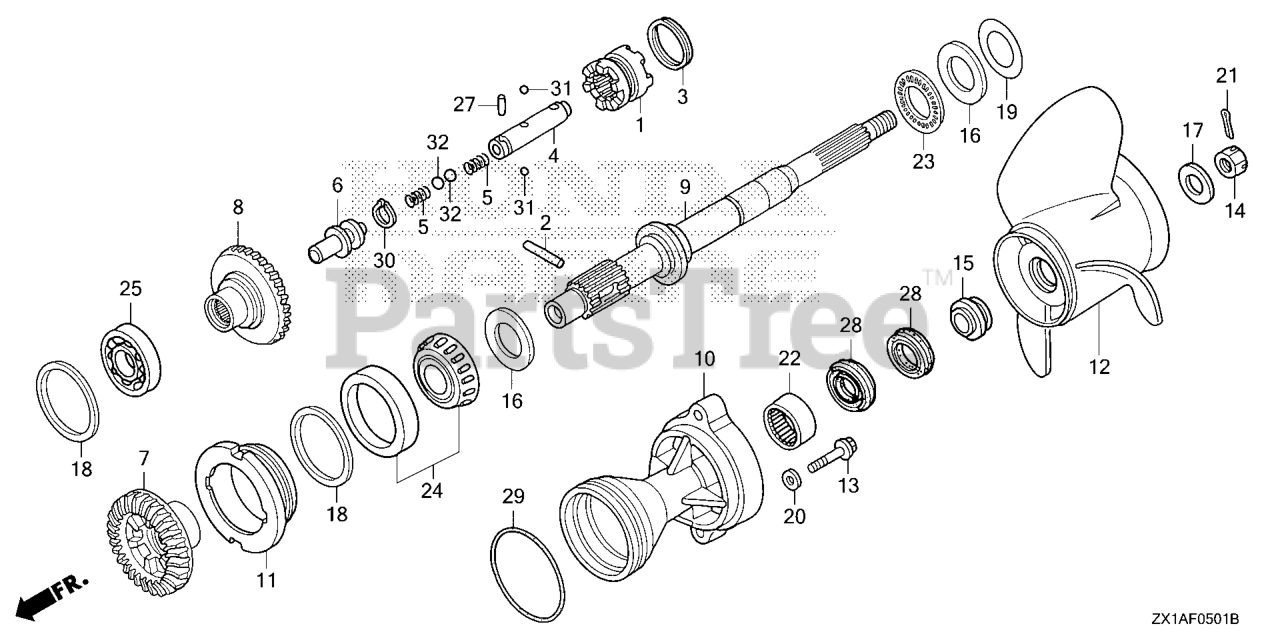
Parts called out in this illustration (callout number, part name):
1	SHIFTER, CLUTCH
2	PIN, SHIFTER (8X47)
3	RING, CROSS PIN
4	SLIDER, SHIFT
5	SPRING, SHIFT
6	PLATE, SHIFT
7	GEAR, BEVEL (FORWARD 30T) (COUNTER ROTATION)
8	GEAR, BEVEL (RVS. 30T) (COUNTER ROTATION)
9	SHAFT, PROPELLER (COUNTER ROTATION)
10	HOLDER, PROPELLER SHAFT *NHB14M* (AQUA MARINE SILVER METALLIC)
10	HOLDER,PROP*NH565*
11	HOLDER, BEARING (COUNTER ROTATION)
12	PROPELLER, THREE-BLADE (14-1/2X15) (C/R)
12	PROPELLER, THREE-BLADE (14-1/4X17) (C/R)
12	PROPELLER, THREE-BLADE (14X19) (C/R)
12	PROPELLER, THREE-BLADE (14X21) (C/R)
12	PROPELLER, THREE-BLADE (14-1/2X23) (C/R)
13	BOLT, FLANGE (10X40)
14	NUT, CASTLE (18MM)
15	WASHER, PROPELLER THRUST
16	WASHER, THRUST BEARING
17	WASHER, PROPELLER
18	SHIM A, BEVEL (0.10)
18	SHIM B, BEVEL (0.15)
18	SHIM C, BEVEL (0.30)
18	SHIM D, BEVEL (0.50)
19	SHIM A, THRUST (0.10)
19	SHIM B, THRUST (0.15)
19	SHIM C, THRUST (0.30)
19	SHIM D, THRUST (0.50)
20	WASHER, PLAIN (10MM)
21	PIN, SPLIT (4.0)
22	BEARING, NEEDLE (30X37X26)
23	BEARING, THRUST (F)
24	BEARING, TAPER (50X90X28)
25	BEARING, RADIAL BALL (50X90X20)
26	BEARING, NEEDLE (25X32X26)
27	ROLLER (3X12.8)
28	SEAL, WATER (30X45X7)
29	O-RING (105X3.1)
30	CIRCLIP (OUTER) (14MM)
31	BALL, STEEL (#7) (7/32)
32	BALL, STEEL (#9) (9/32)
